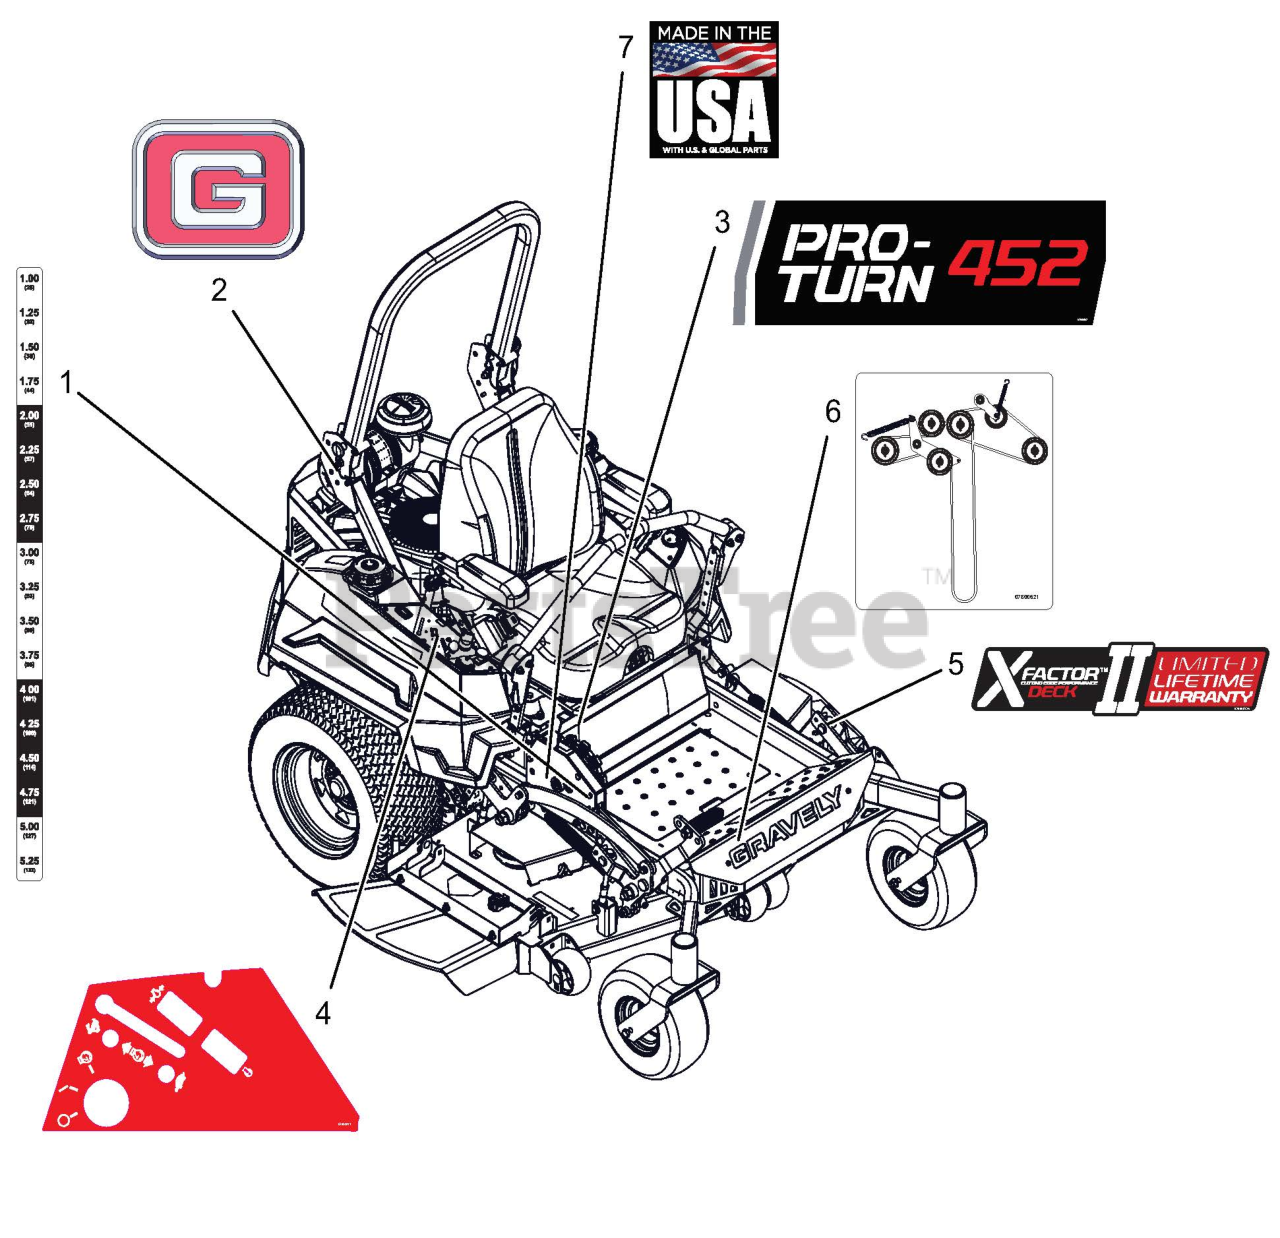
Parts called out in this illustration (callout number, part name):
1	DECAL, PT400 HEIGHT OF CUT
2	DECAL, GRAVELY BRAND
3	DECAL, PRO-TURN 452
4	DECAL, EFI CONTROL PANEL
5	DECAL, X-FACTOR DECK
6	DCL,BELT ROUTE-RH V-SIDE IDLER
7	DECAL, MADE IN USA
